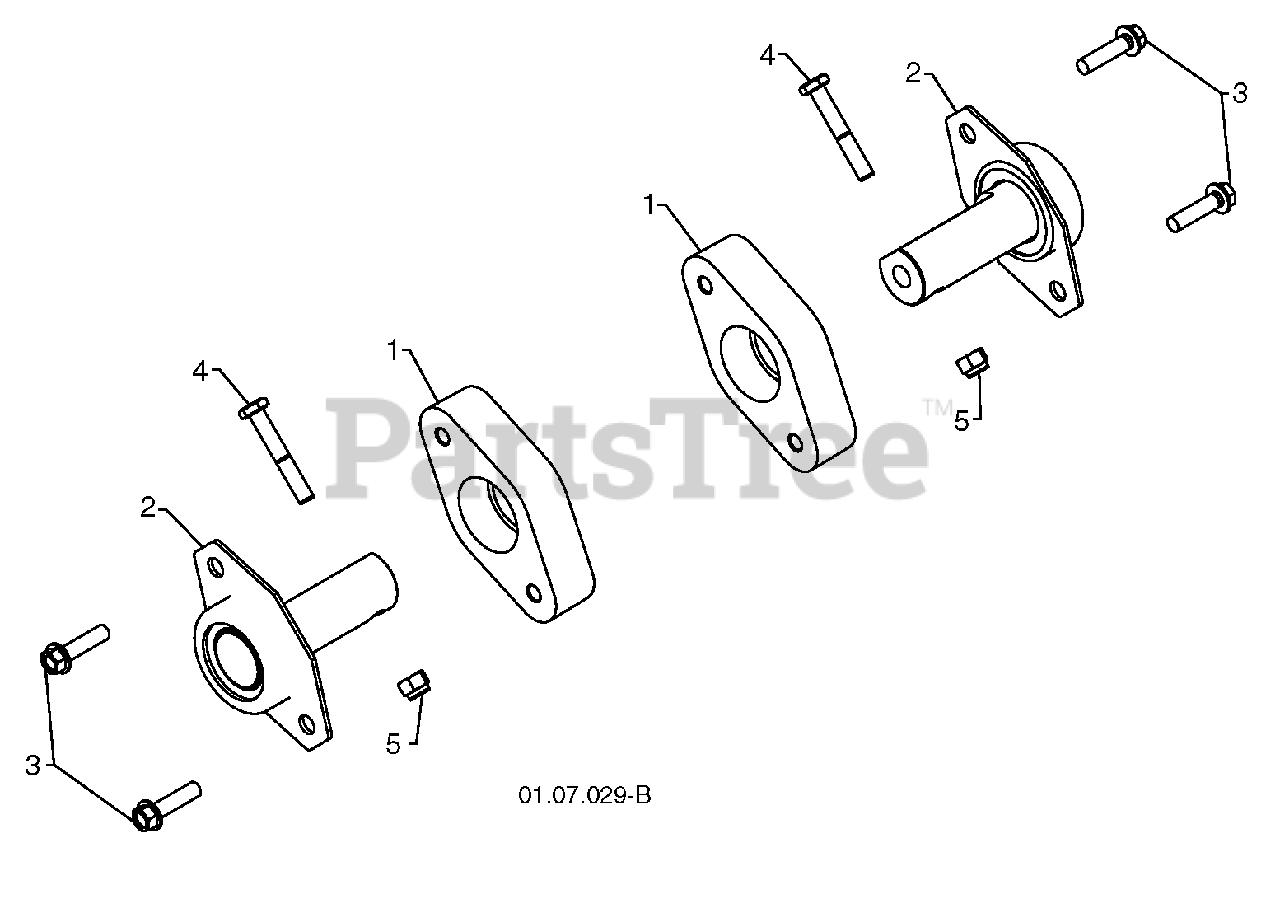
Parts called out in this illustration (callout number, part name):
1	BEARING RETAINER, PLASTIC
2	BEARING.BALL.AUGER.FLAT.
3	SCREW, HEX HD 5/16X1
4	SCREW.HEX.HD1/4-20X
5	LOCKNUT.NYLOC.1/4-20
